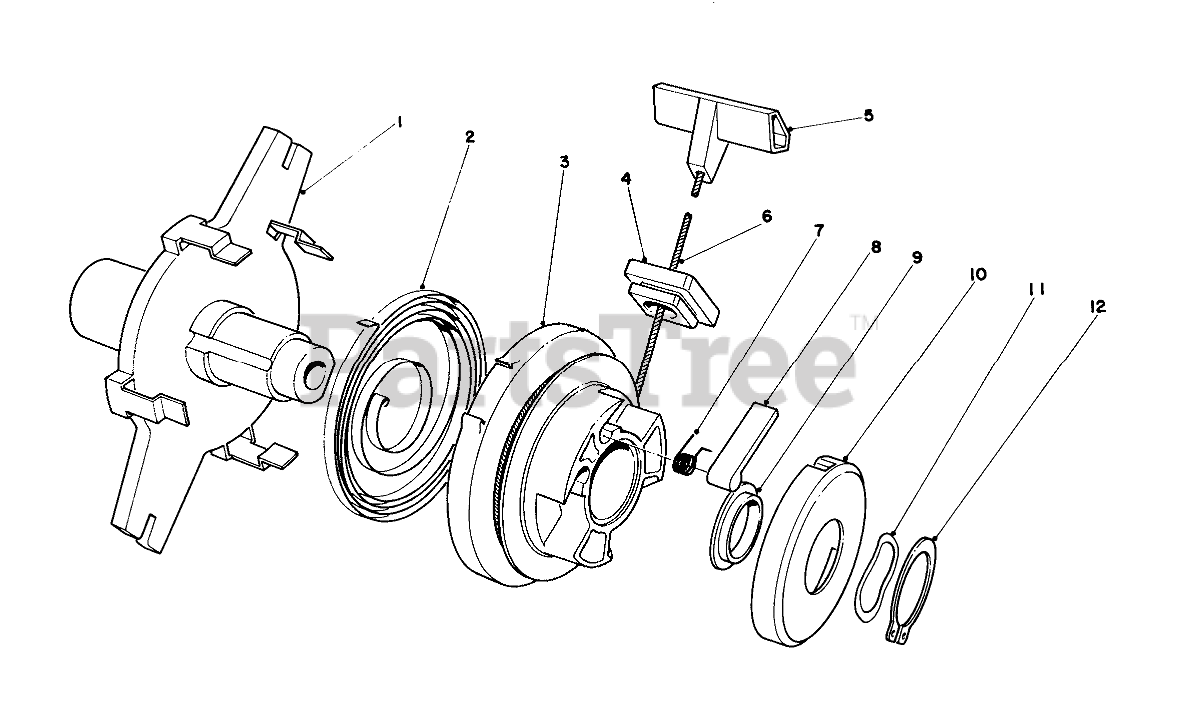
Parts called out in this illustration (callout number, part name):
1	Plate-Starter Backing
3	Drum-Pawl Holder
4	Bushing Rope
5	Handle
6	590 Rope-Starter
7	Spring-Torsion
8	Pawl
9	Collar
10	Cover-Ratchet
11	Washer-Spring
12	RING-Retaining
